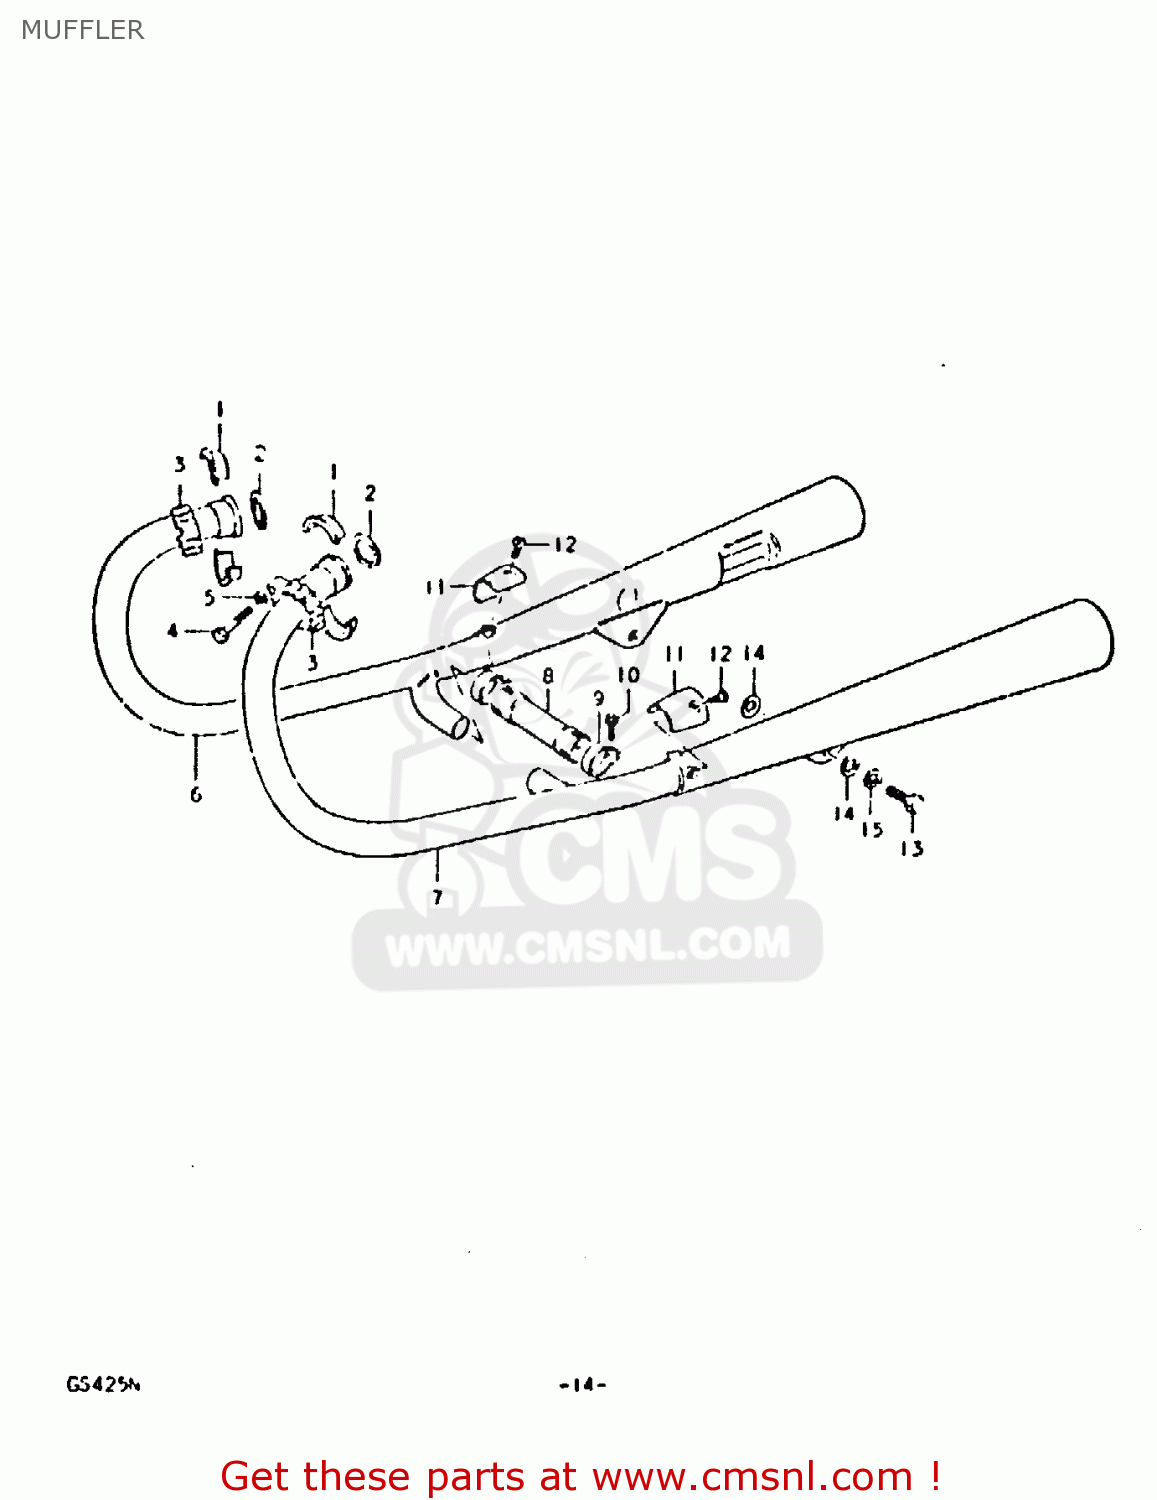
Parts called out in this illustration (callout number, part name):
1	PLATE,EXHAUST P
2	GASKET,EXHAUST PIPE (NAS)
3	CLAMP,EXHAUST PIPE
4	BOLT
5	LOCK WASHER
6	BODY,MUFFLER
7	BODY,MUFFLER
8	PIPE,EXHAUST COUPLER
9	CLAMP
10	BOLT
11	COVER,MUFFLER,RIGHT
12	SCREW
13	BOLT 10X25
14	WASHER
15	LOCK WASHER
